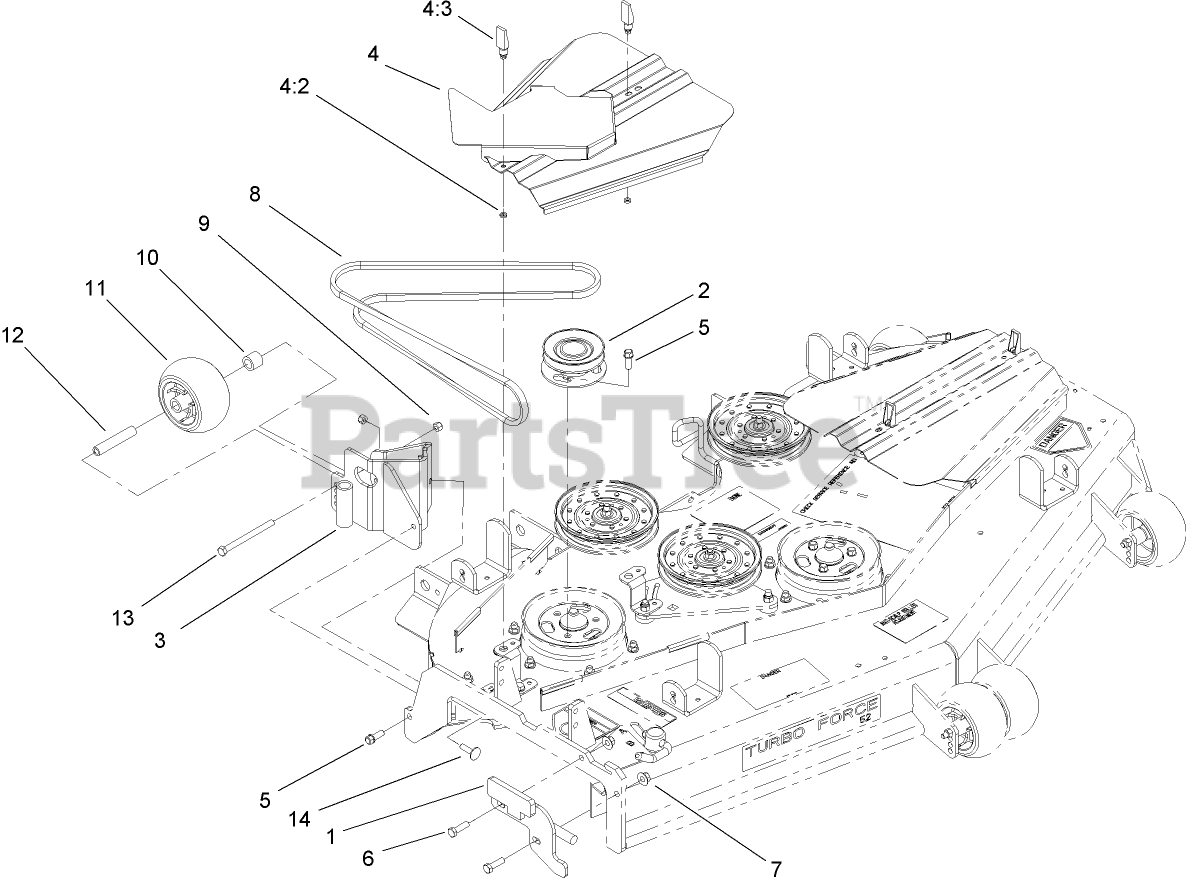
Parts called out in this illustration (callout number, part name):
1	FRONT HINGE ASM
2	PULLEY ASM
3	REAR HINGE ASM
4	BELT COVER ASM
4:2	WASHER
4:3	LATCH-SWELL
5	SCREW-HWH
6	SCREW-HH
7	NUT-FLANGE
8	Belt-V
9	NUT-HHF, WHIZ
10	TUBE-SPACER
11	ROLLER-SCALP, ANTI
12	TUBE-SPANNER
13	SCREW-HH
14	BOLT-CARR
